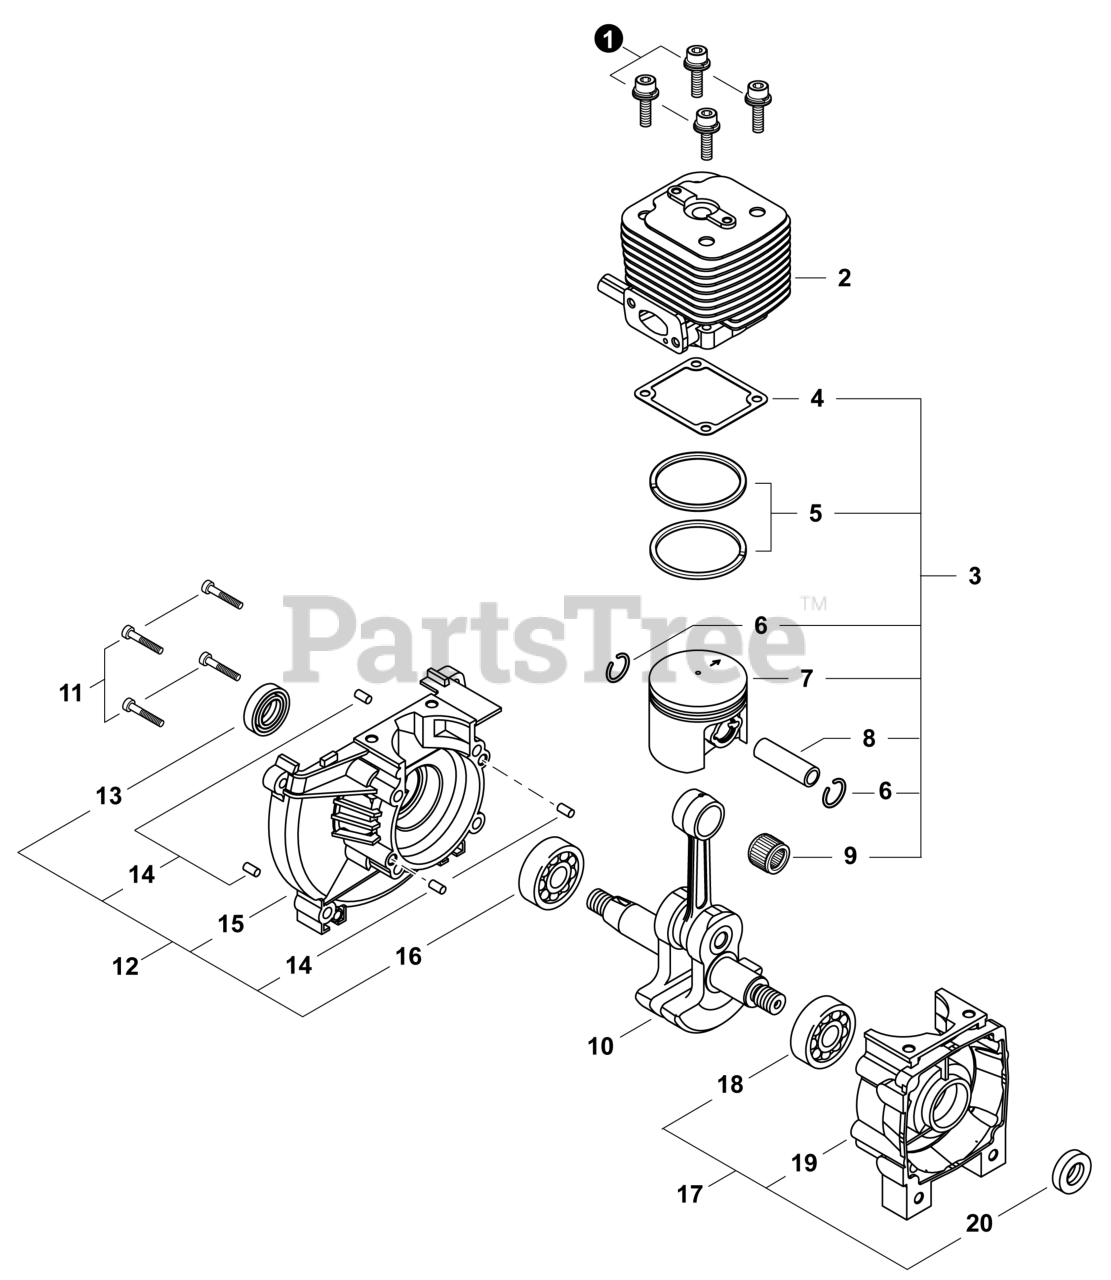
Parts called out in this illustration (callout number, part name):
1	BOLT M5x25
2	CYLINDER
3	PISTON KIT
4	GASKET, CYLINDER
5	RING, PISTON
6	RING, SNAP
8	PIN, PISTON
9	BEARING, NEEDLE
10	CRANKSHAFT
11	BOLT 5x30
12	CRANKCASE ASSY, M
13	SEAL, OIL 16
14	PIN, LOCATING 5x10
15	CRANKCASE M
16	BEARING, BALL 6202 C3
17	CRANKCASE ASSY, S
18	BEARING, BALL 6202 C3
19	CRANKCASE S
20	SEAL, OIL 16
